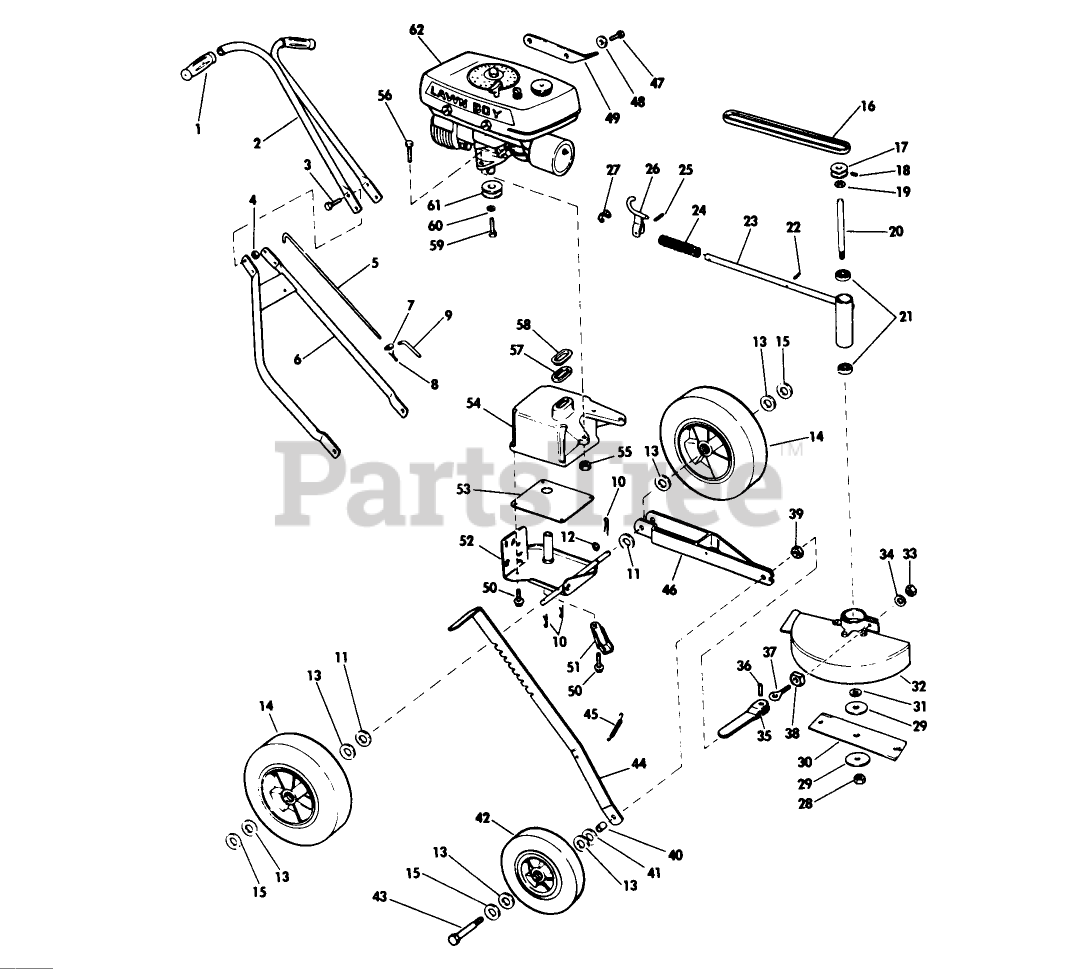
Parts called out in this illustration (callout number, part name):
1	HANDLE GRIP
4	STOP NUT
30	Blade-9"
36	Roll Pin
39	LOCKNUT
46	Wheel Bracket and Spacer Assy.
57	GASKET S
60	WASHER, LOCK
